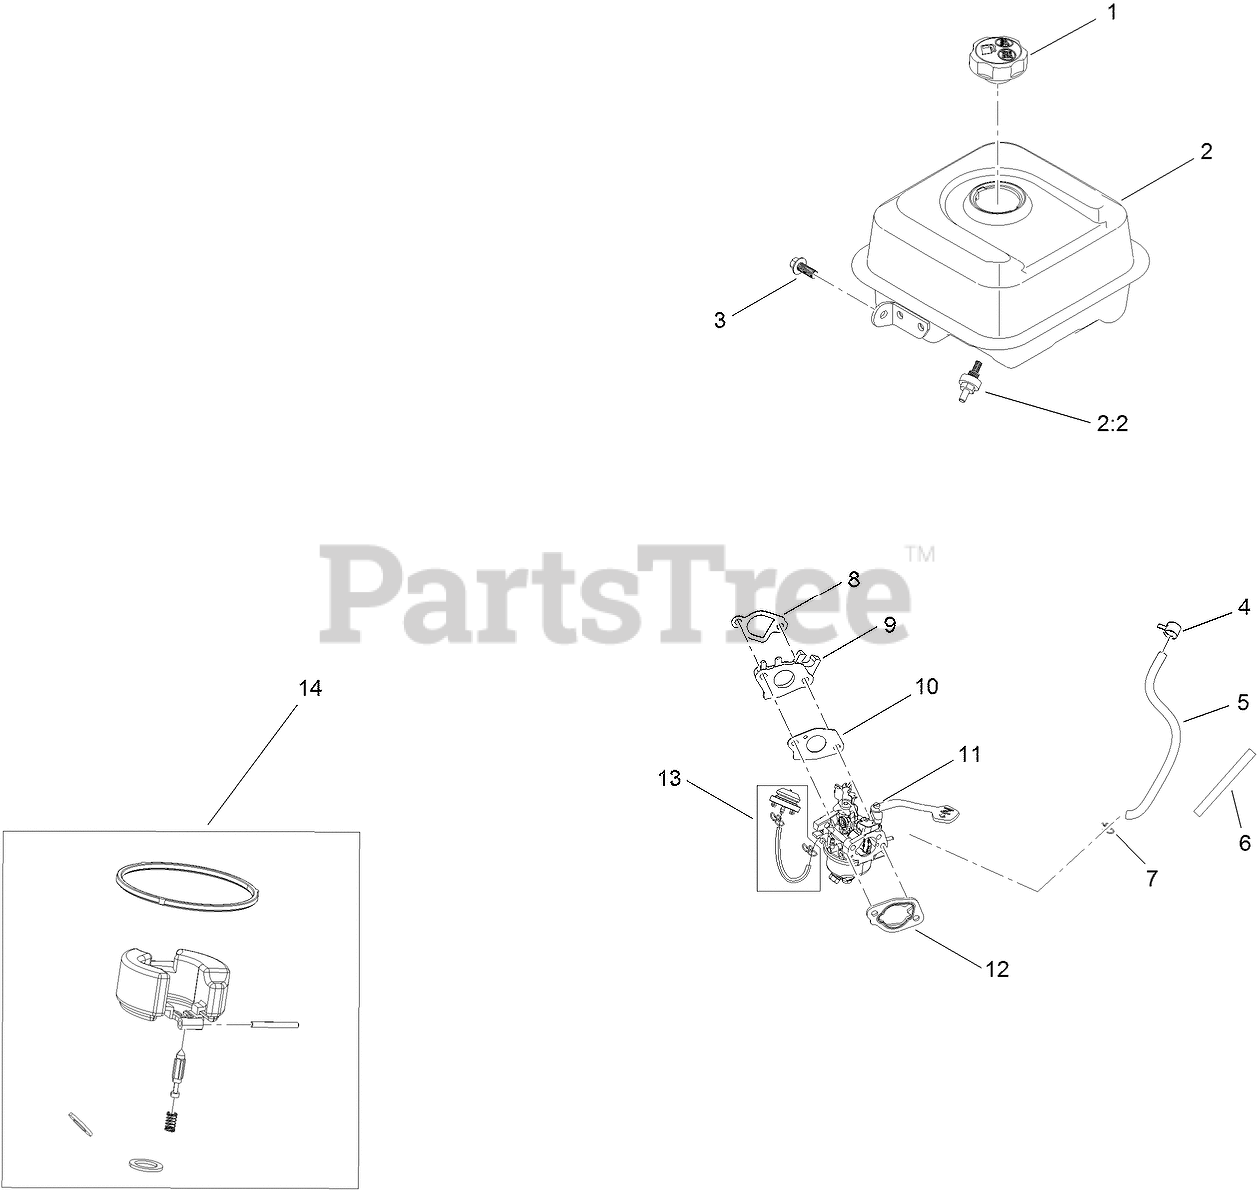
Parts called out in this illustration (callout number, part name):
1	CAP-FUEL (PHASE 3)
2	FUEL TANK AND FILTER ASM
2:2	FILTER-FUEL
3	SCREW-HHF
4	CLAMP-HOSE
5	HOSE-FUEL
6	SLEEVE-ABRASION
7	CLAMP-HOSE
8	GASKET-CARBURETOR
9	INSULATOR-CARBURETOR
10	GASKET-CARBURETOR
11	CARBURETOR ASM
12	GASKET-CARBURETOR
13	PRIMER KIT
14	INTERNAL CARB SERVICE KIT
